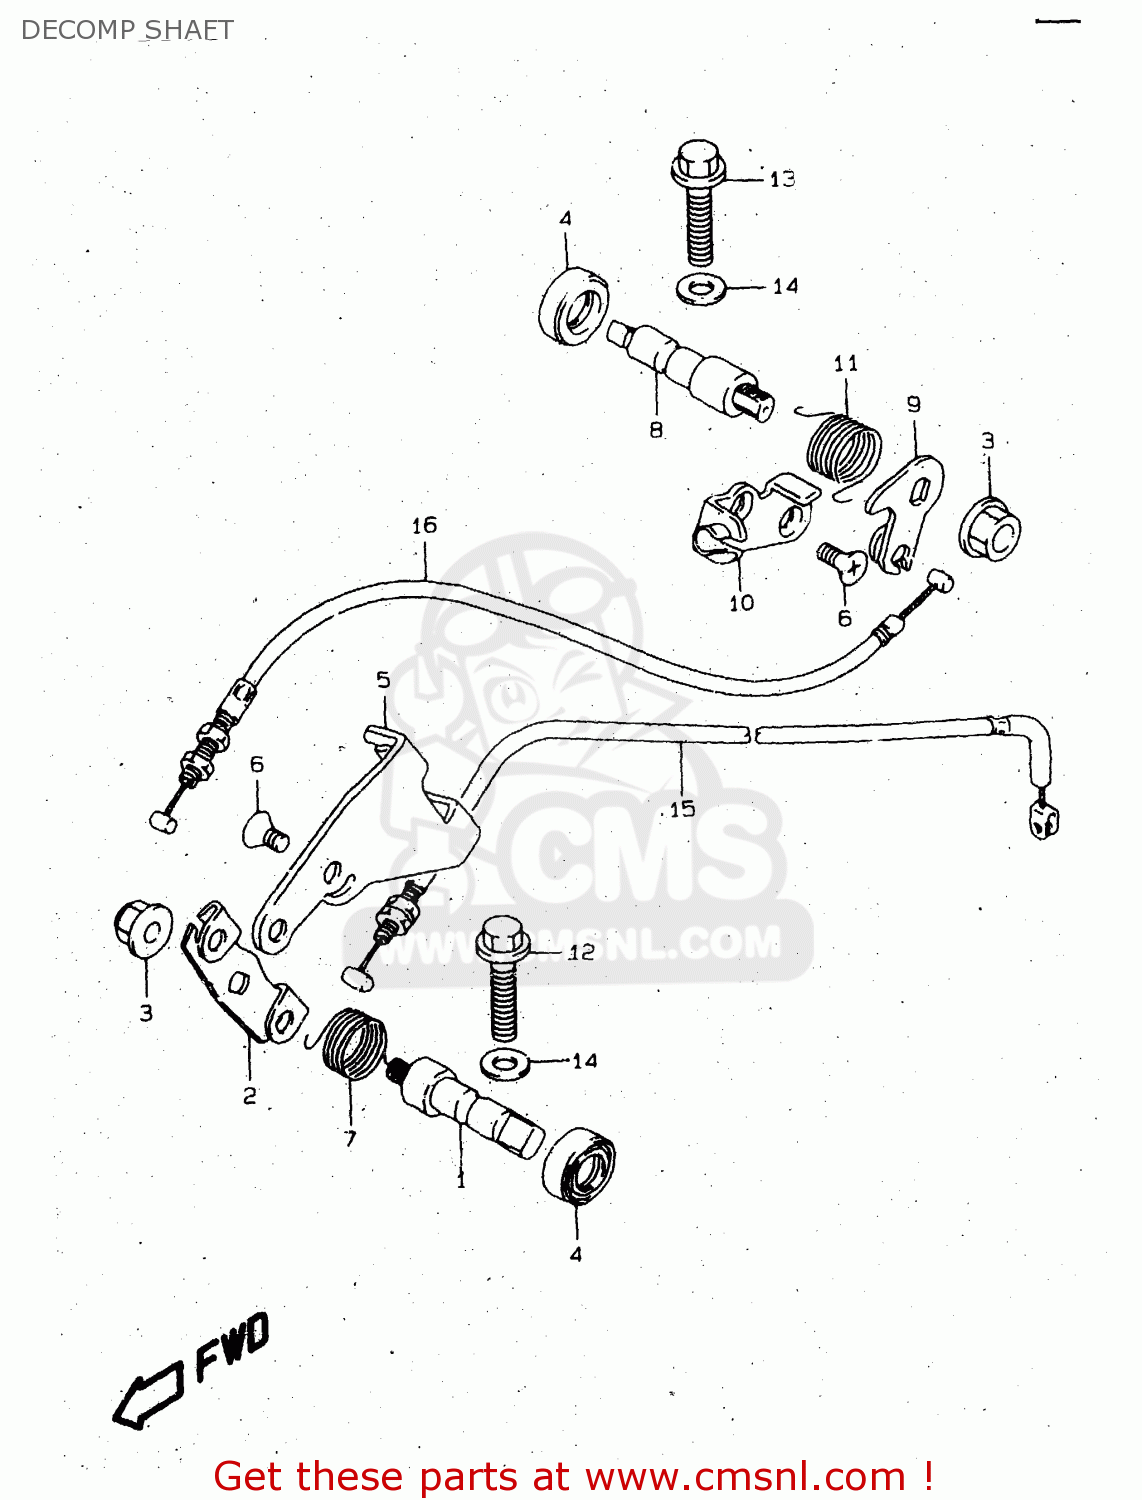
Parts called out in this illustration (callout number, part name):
1	SHAFT,DECOMP FR
2	LEVER,DECOMP SHAFT FR
3	NUT
4	SEAL,OIL(10X20X6)
5	HOLDER,DECOMP CABLE FR
6	SCREW
7	SPRING
8	SHAFT,DECOMP RR
9	LEVER,DECOMP SHAFT RR
10	HOLDER,DECOMP CABLE RR
11	SPRING
12	BOLT
13	BOLT
14	GASKET(5.8X13X1.2) (NAS)
15	CABLE ASSEMBLY,DECOMPRESSION
16	CABLE ASSEMBLY,DECOMPRESSION,REAR
